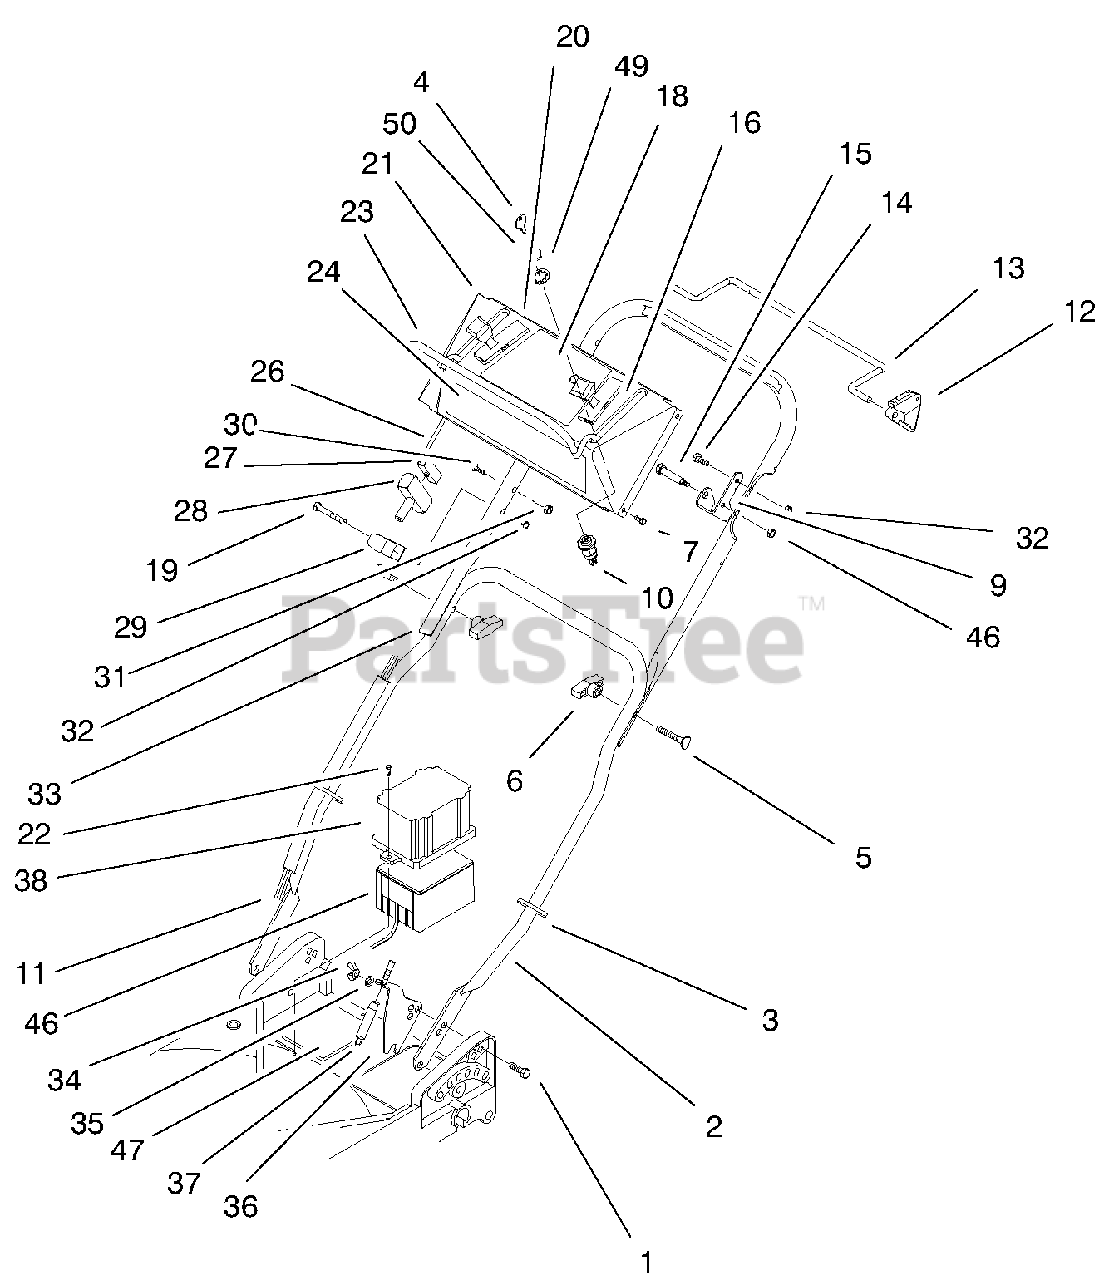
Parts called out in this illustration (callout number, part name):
1	Bolt-CARR
2	Handle Section-Lower
3	Tie Strap
4	Key-Ignition
5	Screw-Handle
7	Screw-Phil
8	Nut-Lock
9	Bail Stop Bracket
10	Switch-Starter
11	ASM-Wire
12	Stop-Pivot
13	Bail-Sp Control
14	Screw-HH
16	Throttle Cable
18	Decal-Control Panel
19	Bolt-Hex
20	Control-Speed
21	Control- Console
22	Screw-Thread Forming
23	Engine Control Bail
24	Decal-Console
26	Cable-Control
27	Clip-Rope
28	Handle-Starter
29	Guide-Rope
30	Handle Screw
31	Bracket-Cable Anchor
32	Nut-Lock
33	Handle-Upper
35	Washer-Lock
36	Bracket-Traction Cable
38	Case-Battery
46	Battery Pack
47	Pad Battery
48	Charger-Battery
49	Washer-Lock
50	Nut-HH (F/W Sw)
